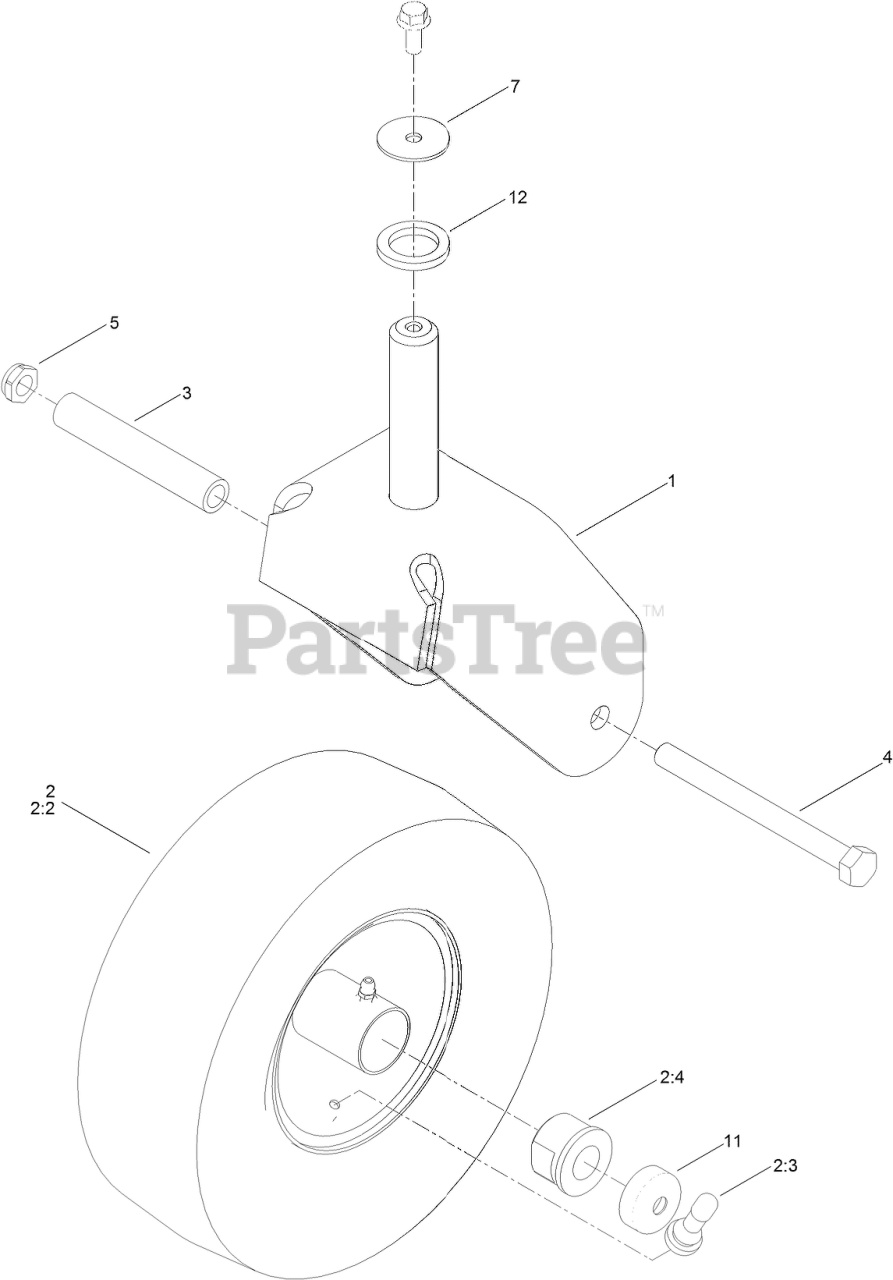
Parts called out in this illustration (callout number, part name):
1	FORK ASM
2	TIRE AND WHEEL ASM
2:4	BEARING
3	SPANNER-WHEEL
4	SCREW-HHF
5	NUT-LOCK
7	WASHER-FLAT
11	GUARD-SEAL
12	WASHER
